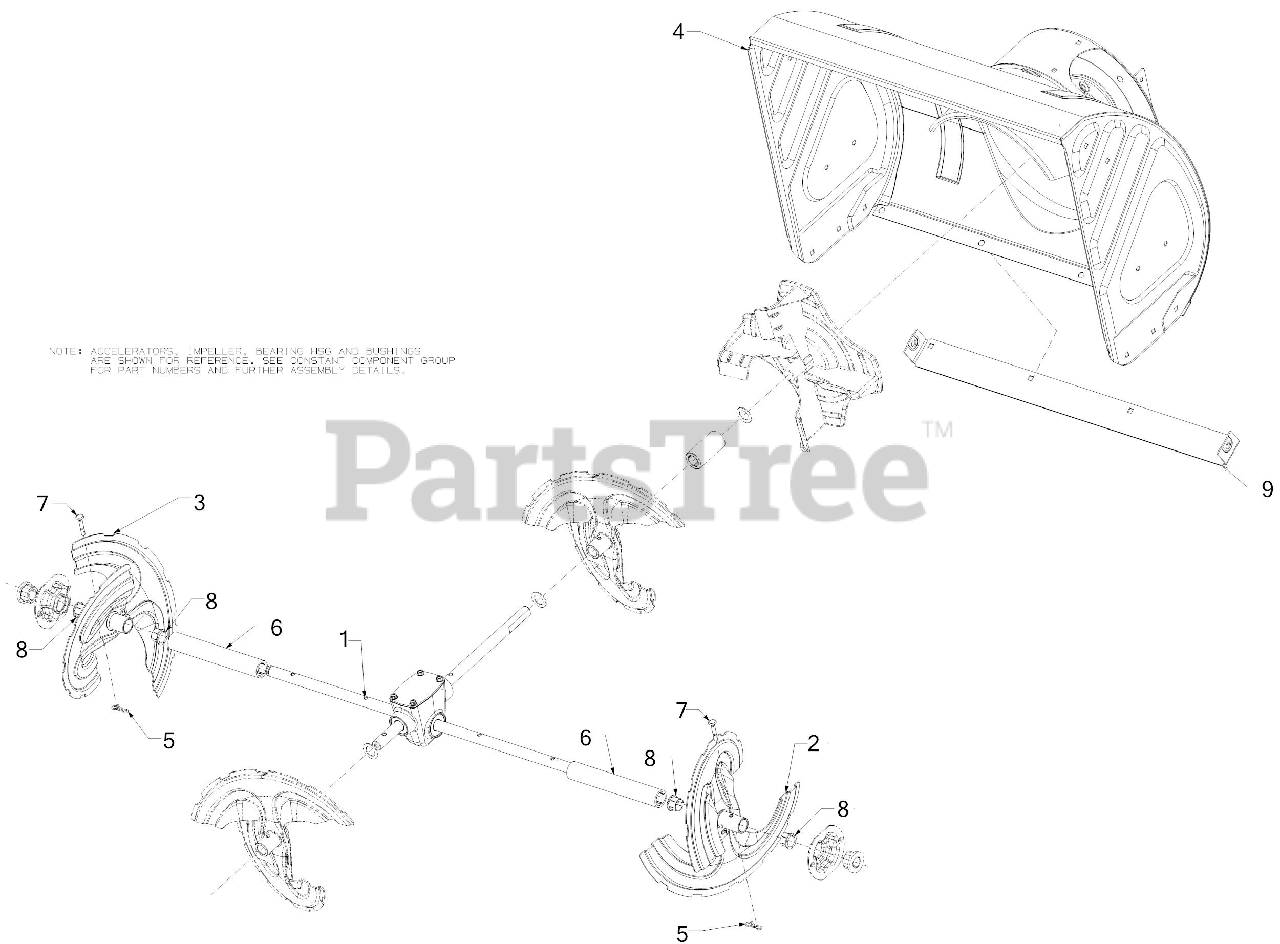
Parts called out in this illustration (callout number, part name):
1	28" AUGER GEARBOX ASSEMBLY
5	BOW TIE COTTER PIN 1/4-5/16
7	SHEAR PIN .25 x 1.50 GR2
8	FLANGE BUSHING
